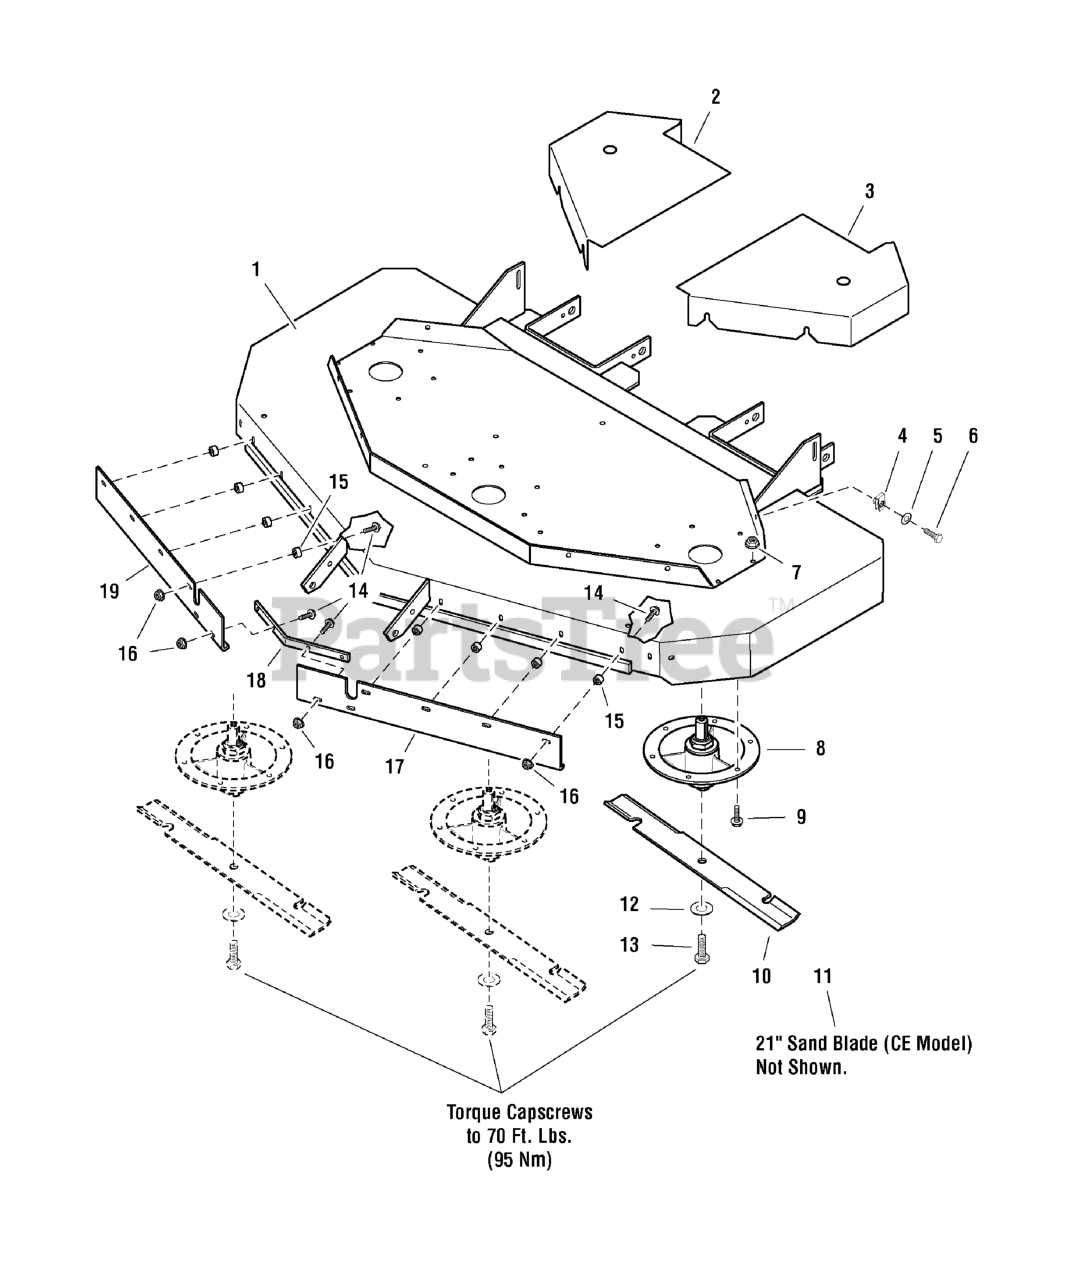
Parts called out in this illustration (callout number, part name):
1	DECK SHELL W/DECALS, 61" REAR DISCHARGE
2	DECK SHIELD - RH
3	DECK SHIELD - LH
4	BODY CLIP, 5/16-18-7GA MATERIAL
5	WASHER, 5/16" SAE
6	BOLT, 5/16-18 X 3/4 GD5
7	NUT, 3/8-16 Hex Nylock Flange
8	SPINDLE ASSEMBLY
9	BOLT, 3/8-16 X 1-1/4, FLANGE, GD 5, CZ
10	MOWER BLADE, 21"
11	MOWER BLADE, SAND, 21"
12	WASHER, 5/8" GRADE 8, YZ
13	BOLT, 5/8-11 X 1-3/4 GD8
14	BOLT, Flange Head, 5/16-18 x 1-1/4
15	SPACER, .39 X .75 X .50, CZ
16	NUT, 5/16-18 Hex Nylock Flange
17	BLOWOUT BAFFLE - LH
18	BAFFLE, REINFORCEMENT - BLK
19	BLOWOUT BAFFLE - RH
